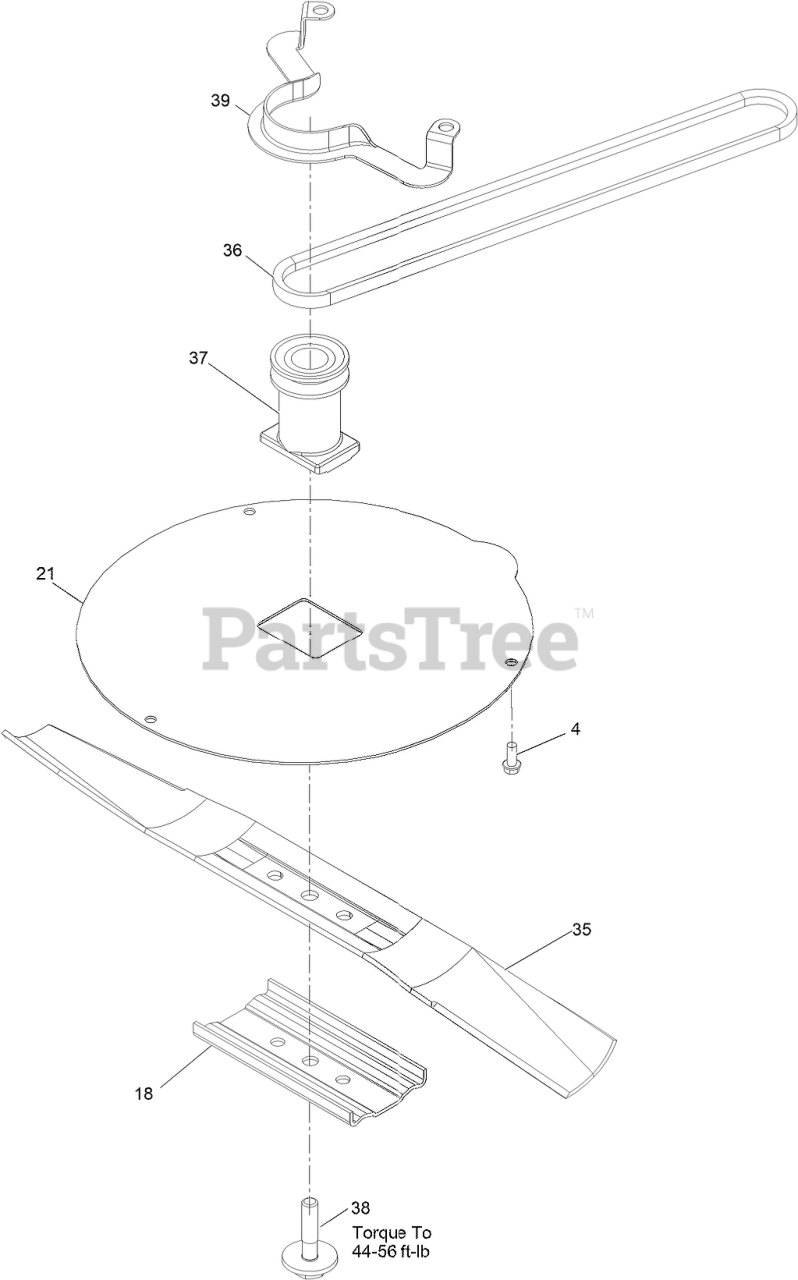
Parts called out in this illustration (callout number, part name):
4	SCREW-HWH
18	SUPPORT-BLADE
35	BLADE-BAGGING 21 IN
36	BELT,3L P21 DRIVE
37	BLADE-ADAPTER
38	BOLT-BLADE, SEM
39	GUIDE-BELT
